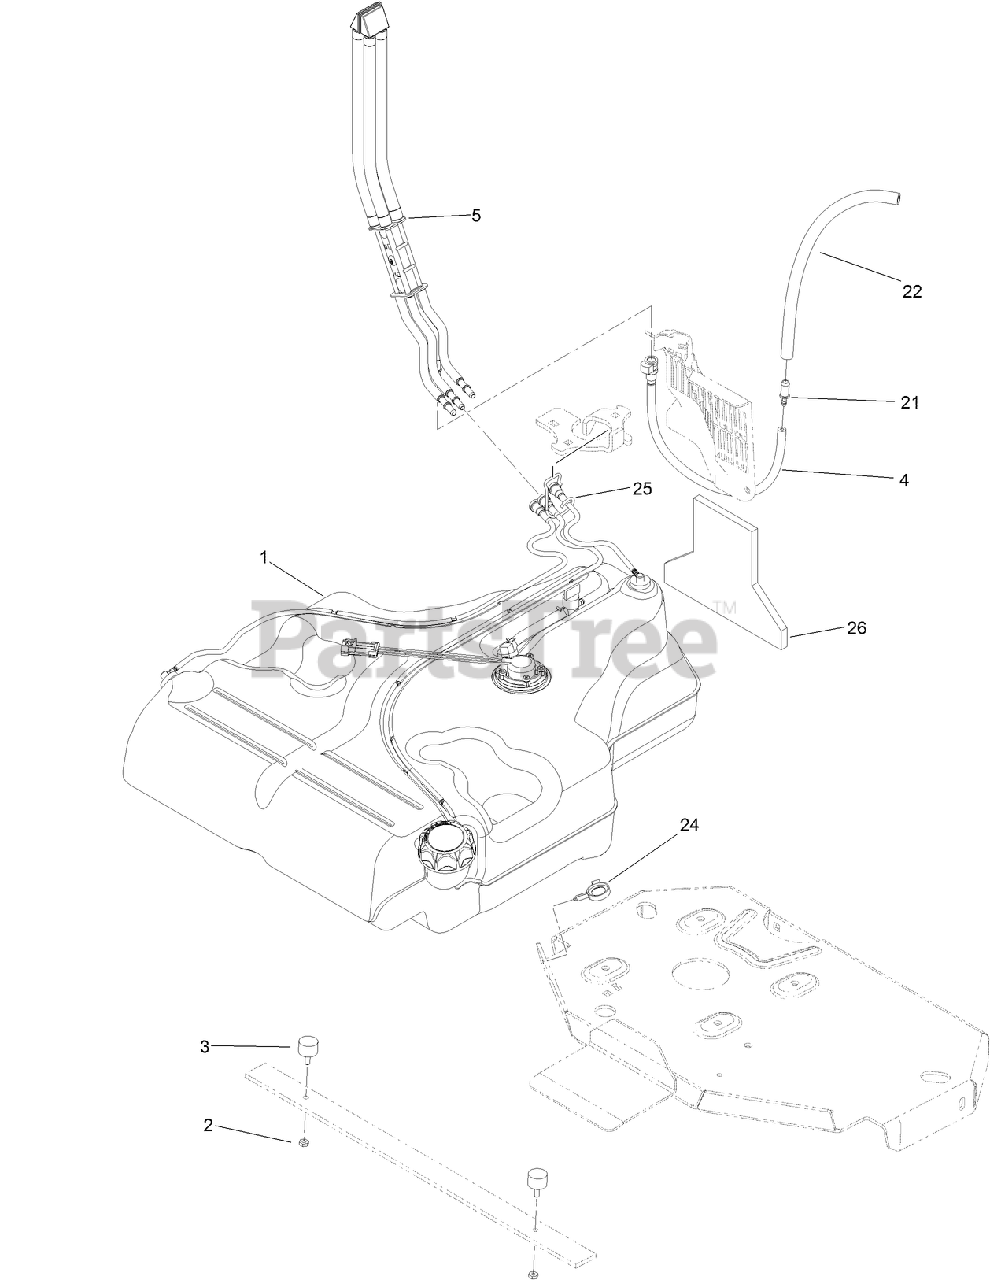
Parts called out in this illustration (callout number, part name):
1	FUEL TANK ASM
2	NUT-JAM
3	BUMPER-RUBBER (W/ STUD)
4	HOSE ASM
5	FUEL MANIFOLD VENT ASM
21	FITTING-STRAIGHT
22	HOSE-FUEL
24	CLAMP-HOSE
25	RETAINER-LINE, VAPOR
26	INSULATION-FOAM, FUEL TANK
